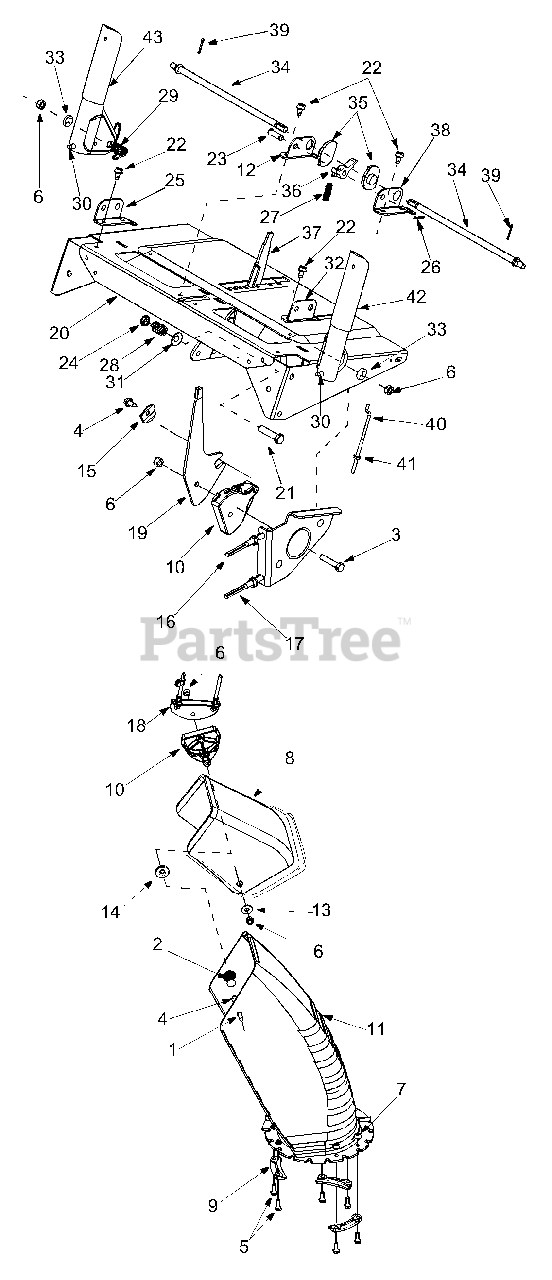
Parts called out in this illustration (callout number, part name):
1	Carriage Screw
2	Carriage Bolt 5/16-18 x 1.75"
3	Hex Bolt 5/16-18 x 1.5"
4	Hi Lo Screw 1/4-15 x .75"
5	Hex Screw 1/4-20 x .75"
6	Hex Lock Nut
7	Hex Flange Lock Nut
8	Upper Chute
9	Chute Flange Keeper
10	Cable Guide: Chute Tilt
11	Lower Chute
13	5/16 Washer
15	Special Washer
16	Chute Control Cable
17	Chute Cable w/Clip
21	Hex Bolt 3/8-24 x 1.5"
22	TT Screw 1/4-20 x 0.5"
23	Clevis Pin
26	Cotter Pin
29	Torsion Spring
30	Rubber Bumper
31	Bell Washer
33	Special Washer
35	Cam: Handle Lock
36	Pawl: Handle Lock
39	Cotter Pin
40	Z Fitting Cable
41	Hex Jam L-Nut 3/8-24 Thd.
42	Handle Ass'y LH
43	Handle Ass'y RH
